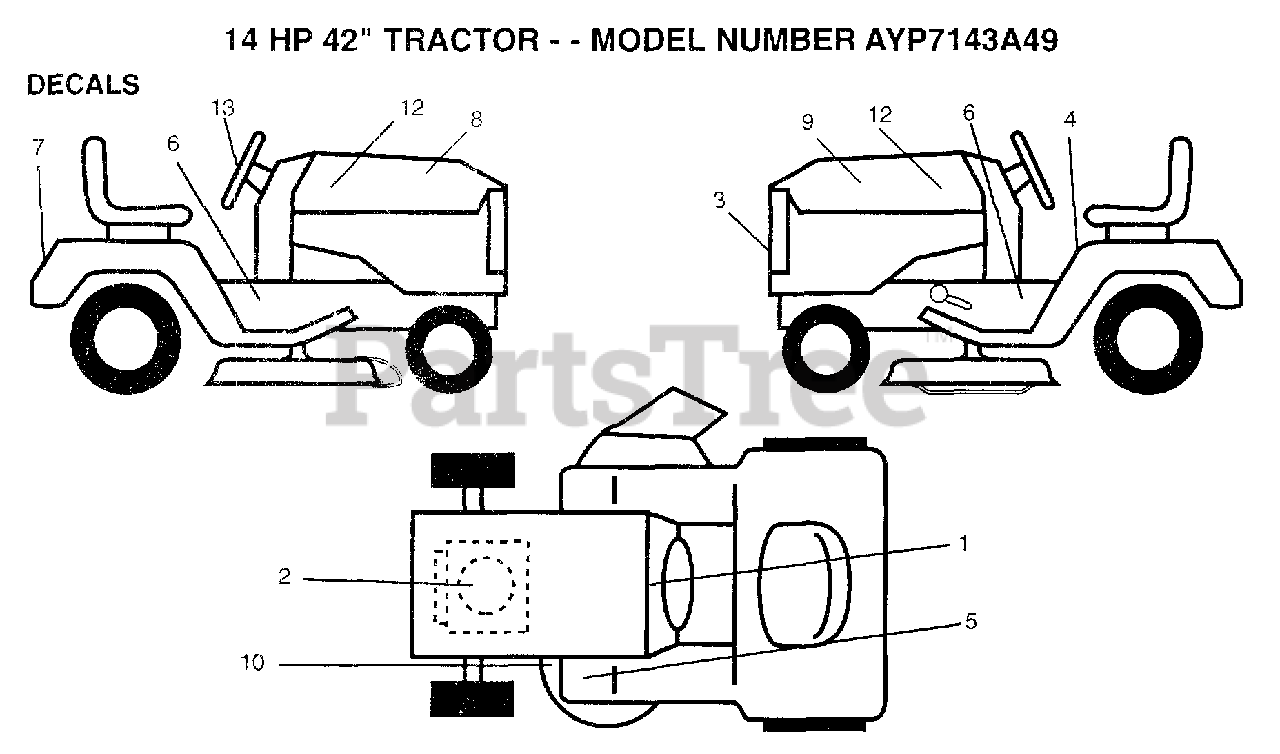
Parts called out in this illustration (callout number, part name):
1	DECAL.DASH.INST.
2	DECAL.ENG.272750
3	DECAL GRILL WIZ
4	DECAL
6	DECAL CHASSIS WIZ
8	DECAL HOOD RH WIZ
9	DECAL HOOD LH WIZ
10	DECAL
12	DECAL HOOD INSERT
